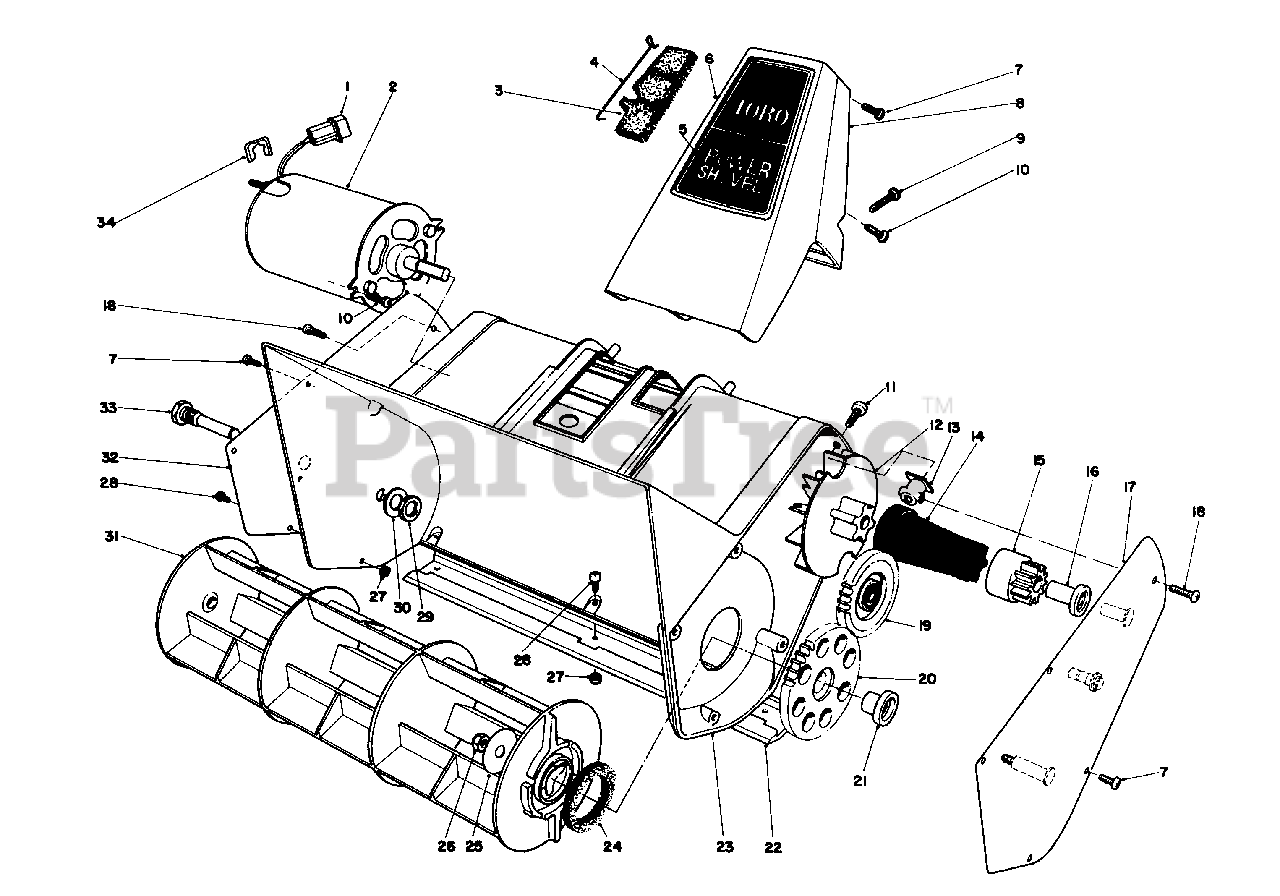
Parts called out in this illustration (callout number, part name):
1	Pin-Housing (Model #38310)
2	Motor (Model #38310)
3	Filter-Foam
4	Retain-Filter
5	Decal-Handle Support
6	Handle Support-Front
7	Screw-Pan Hd.
8	Handle Support-Back
9	Screw-Pan Head
10	Screw-Pan Head
11	Screw-Phillips Truss
13	Block-Mounting
14	Coupling-Drive
15	Drive Gear (Incl. Ref. #16)
16	Bushing-Gear Drive
17	Gear Carrier
18	Screw-Pan Head
19	Idler Gear Assembly
20	Rotor Gear Assembly (Incl. Ref. #21)
21	Bushing-Rotor
22	Scraper
23	Housing (Model #38310)
24	Washer-Felt
25	Washer-Rotor
28	Screw-Pan Head
30	Flat Washer
32	Cover-Right Side
33	Pin-Rotor
34	Strain Relief (Model #38305C)
